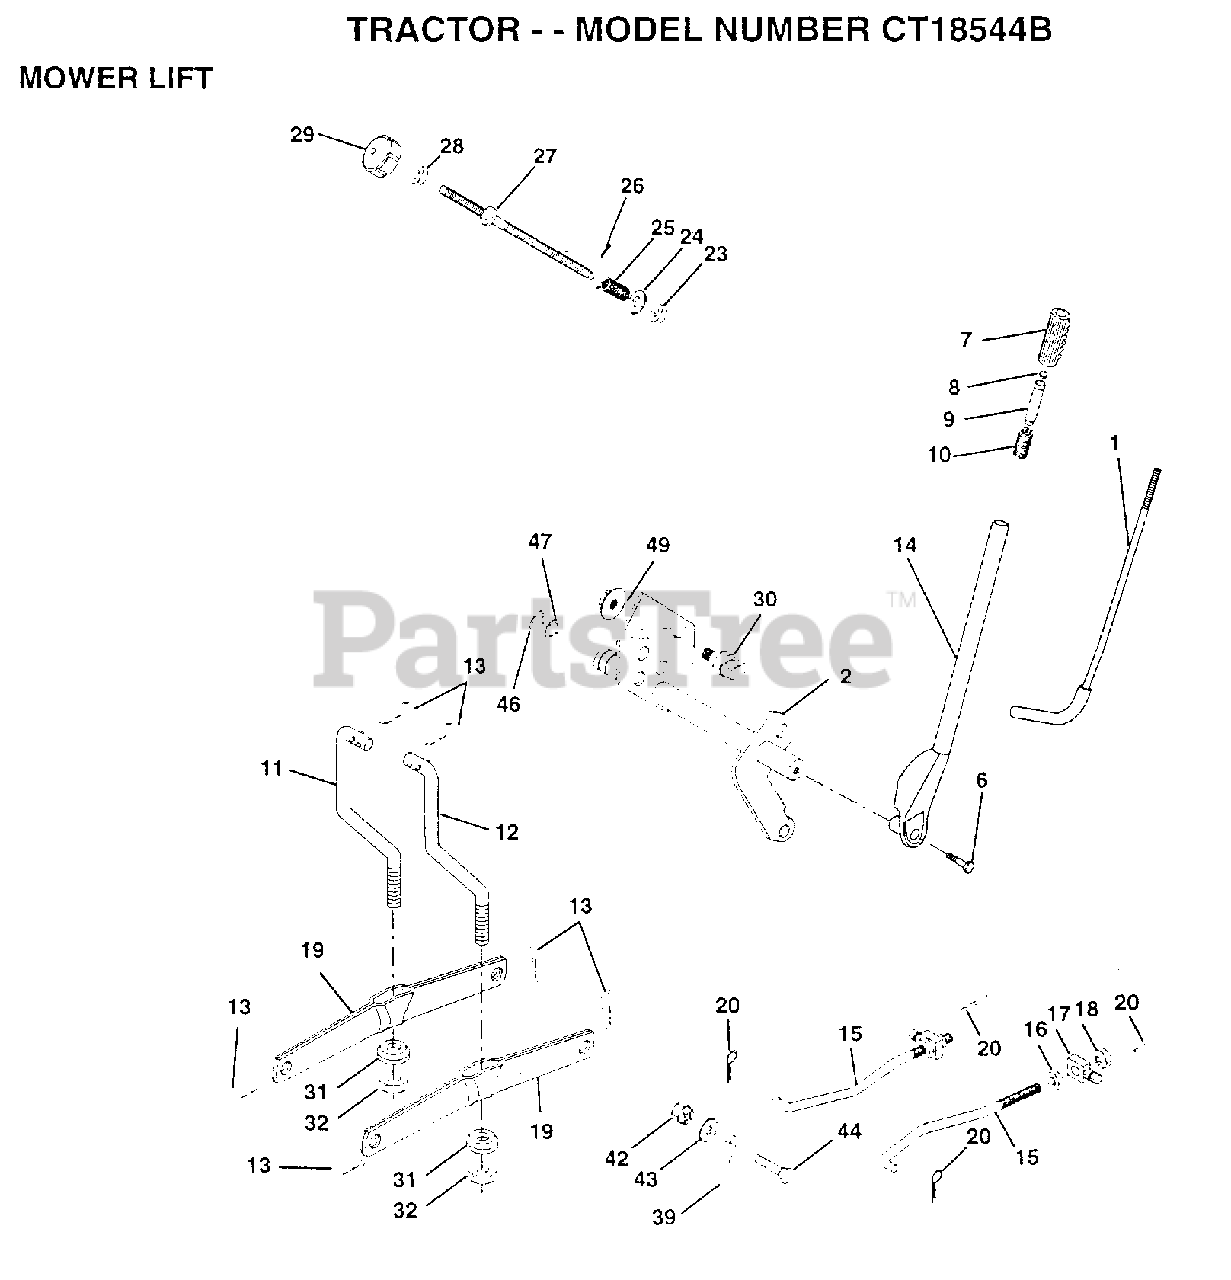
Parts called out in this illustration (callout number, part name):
1	LEVER ROD LT
2	SHAFT LIFT W/IND
6	"BOLT,HEX"
7	GRIP
10	SPRING T
11	LINK.LIFT.LH.GTV
12	LINK.LIFT.RH.GTV.
15	LINK.FRONT
16	NUT
17	TRUNION
18	NUT.LK.W/WSH.1/2.
19	ARM SUSP REAR
20	RETAINER.SPRING
23	NUT T
24	WASHER
25	SPRING.COMP.INF.H
27	ROD.ADJ.LIFT
28	NUT
29	KNOB INF 3/8-16
30	TRUNNION
31	BEARING PVT LH
32	NUT.CROWNLOCK.3/8
39	STOP.OVER.CENTER
43	WASHER GT
44	BOLT
46	E-RING
47	WASHER
49	NUT.HXFLG.LOCK.
